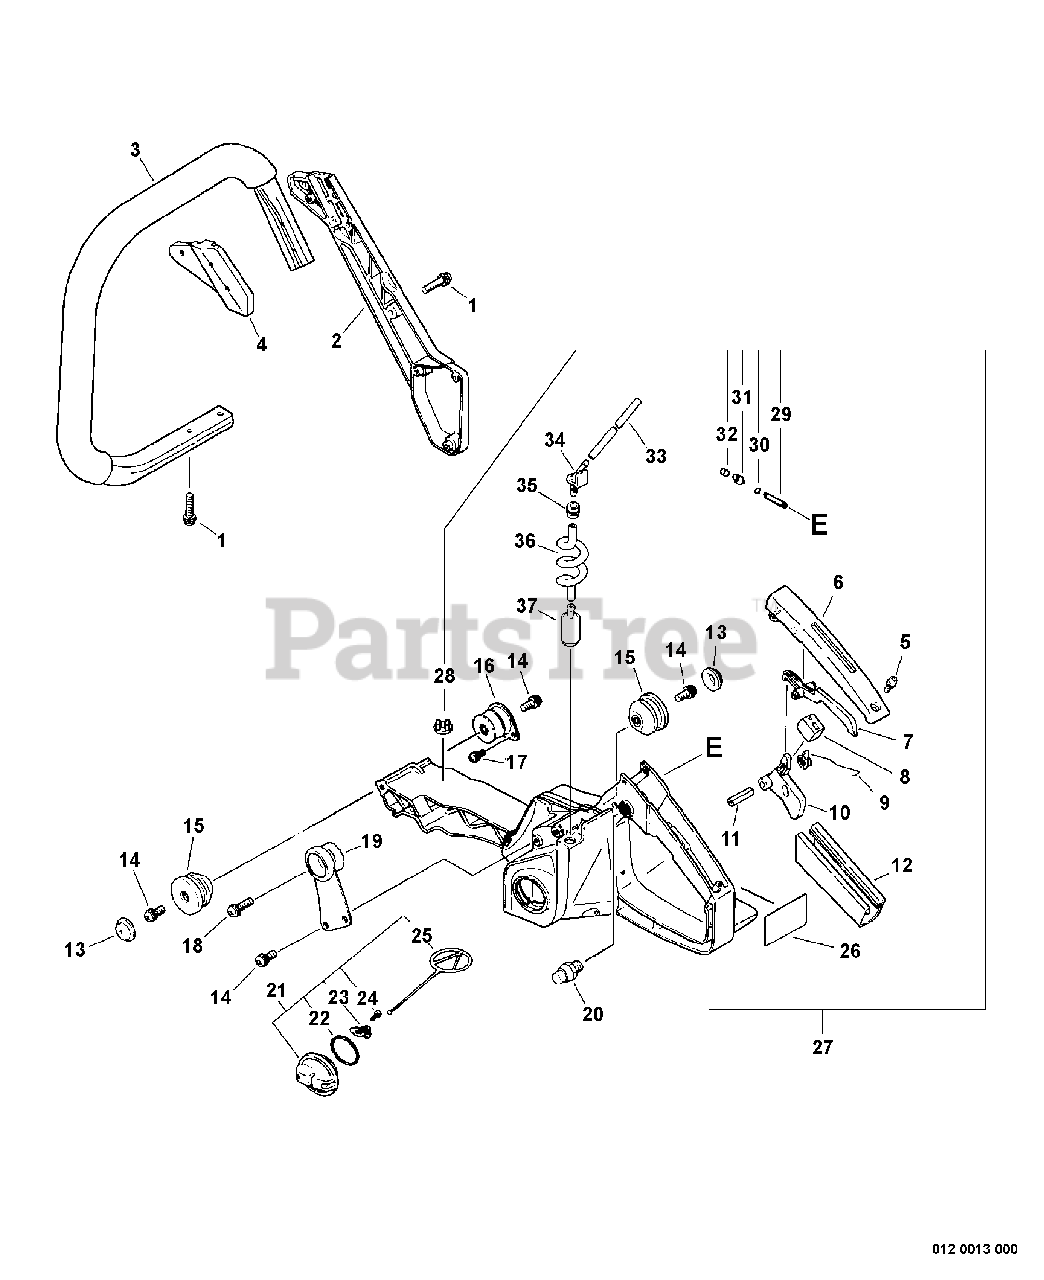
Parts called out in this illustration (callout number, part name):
1	SCREW - 5X20
2	BRACKET, HANDLE
2	BRACKET, HANDLE - ORANGE
3	HANDLE - FRONT
4	BRACKET, HANDLE
4	BRACKET, HANDLE - ORANGE
5	SCREW - 4X14
6	COVER, HANDLE
7	LEVER, TRIGGER LOCKOUT
9	SPRING, TRIGGER
10	TRIGGER, THROTTLE
11	PIN - SPRING -- 5X25
12	GRIP, HANDLE
13	CAP, CUSHION
14	SCREW - 5X14
17	SCREW - 4X10
18	SCREW - 5X20
20	LATCH, THROTTLE
21	CAP ASSY
22	O-RING - 29
23	RETAINER
24	SCREW - 3X8
25	CONNECTOR, CAP
26	LABEL - CAUTION
27	HANDLE - REAR
27	HANDLE ASSY - REAR -- ORANGE
29	PIPE - 3X5X55 -- BLACK
30	CLIP - 5.5
31	COVER, VENT
32	VENT, FUEL TANK
33	PIPE - 3X6X120 -- BLACK
34	CONNECTOR, PIPE
35	GROMMET
36	PIPE - BLACK
37	FILTER, FUEL
